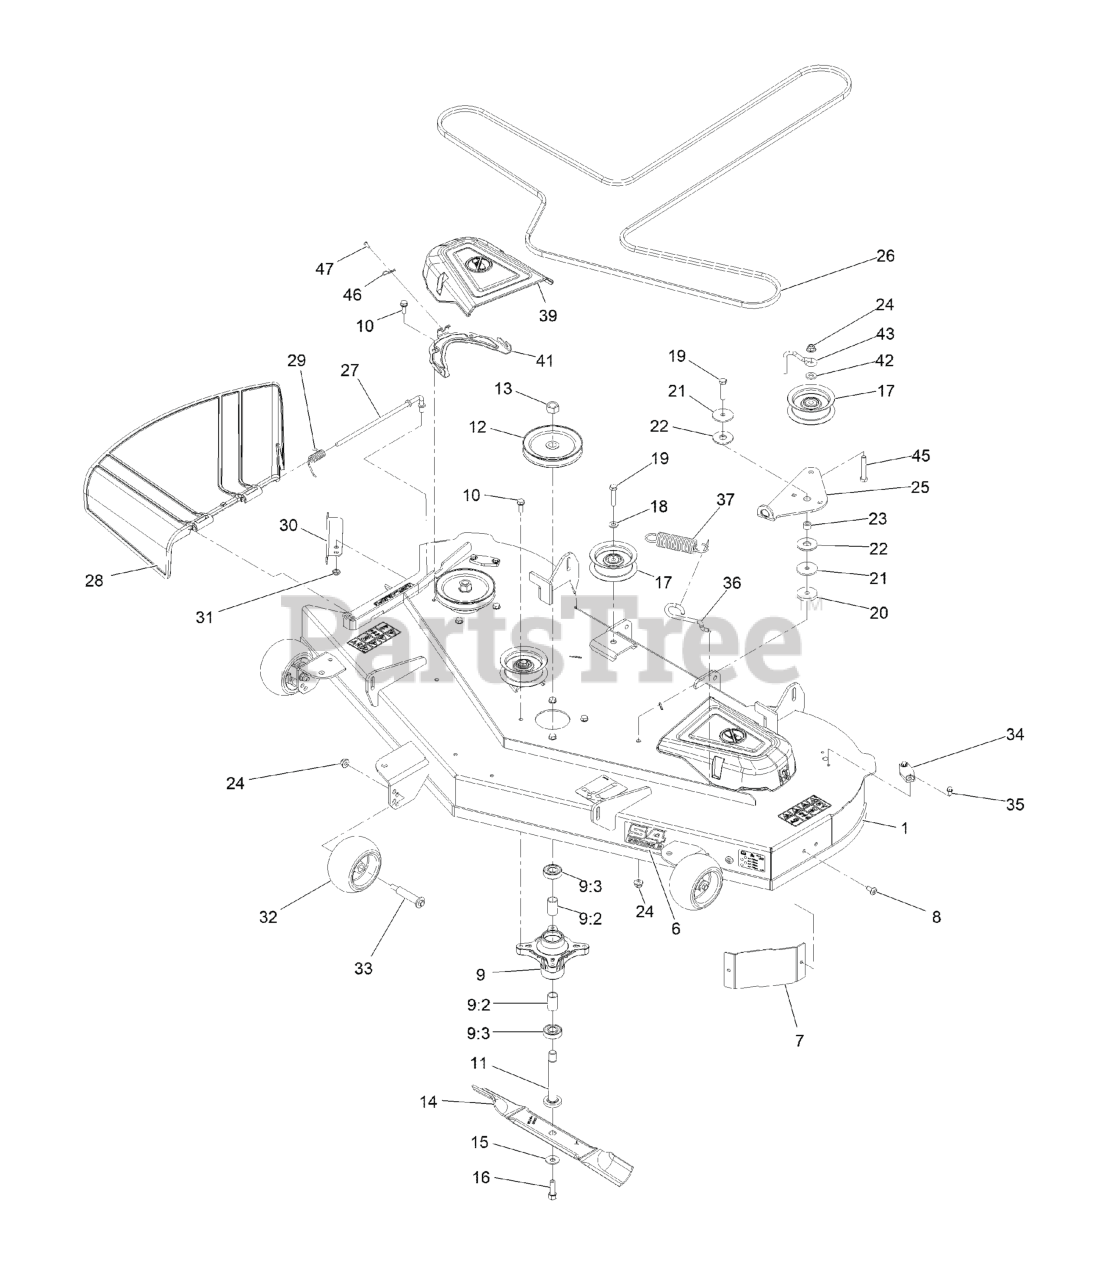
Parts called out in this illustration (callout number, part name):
1	DECK ASM-54 4PT
6	DECAL-54 SERIES 2
7	BAFFLE-CORNER
9	SPINDLE ASM
9:3	BEARING-BALL
10	SCREW-TAPTITE
11	SHAFT-SPINDLE
12	PULLEY ASM
13	NUT-HEX
14	BLADE-HI LIFT
15	WASHER-BELLEVILLE
16	SCREW-HH
17	PULLEY-IDLER, FLAT
18	WASHER-FLAT
19	SCREW-HH
20	WASHER-PLAIN
21	WASHER-REBOUND
22	WASHER-FRICTION, COMPOSIT
24	NUT-HF, NI
25	Arm-Idler
26	BELT-V
27	ROD-PIVOT
28	DEFLECTOR-DISCHARGE
29	SPRING-TORSION
30	BAFFLE-CUTOFF
32	ROLLER-SCALP, ANTI
33	BOLT-SHOULDER
34	COVER-WASHOUT PORT
35	SCREW-HWH
36	Hook-Return Spring
37	SPRING-EXTENSION
39	COVER-BELT
41	BRACKET-COVER, BELT
42	SPACER-HUB, BLOWER
43	Belt Guide - Idler
45	SCREW-HH
46	PIN-HAIR
